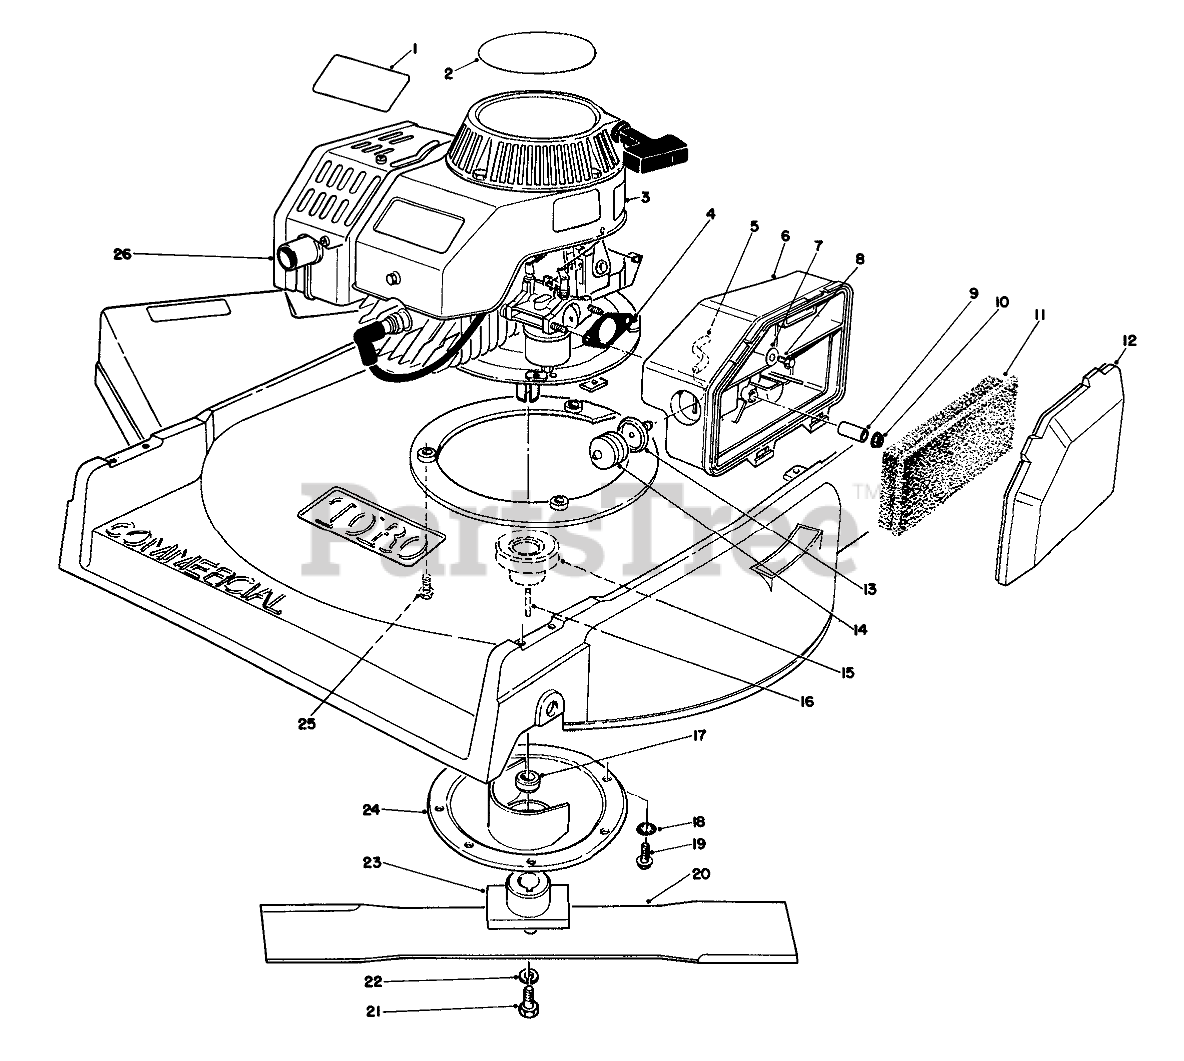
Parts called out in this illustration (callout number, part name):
1	DECAL - PROLINE
2	DECAL-2 CYC RECOIL COMM
3	DECAL - FUEL
4	GASKET-AIR CLEANER
5	HOSE-PRIMER
6	BODY-AIR CLEANER
7	WASHER-FLAT
8	SCREW-HH
9	SPACER
11	ELEMENT-AIR CLEANER
12	COVER-AIR CLEANER
13	BODY-PRIMER
14	BULB-PRIMER
15	PULLEY-DRIVER
16	KEY-SQUARE
17	BLADE SPACER
18	WASHER-LOCK, INTERNAL
19	SCREW-HWHTF
20	BLADE
21	SCREW-BLADE
22	WASHER-LOCK
23	BLADE RETAINER WA
24	PROTECTOR-CRANKSHAFT
25	SCREW-HHF
26	ENGINE ASM
